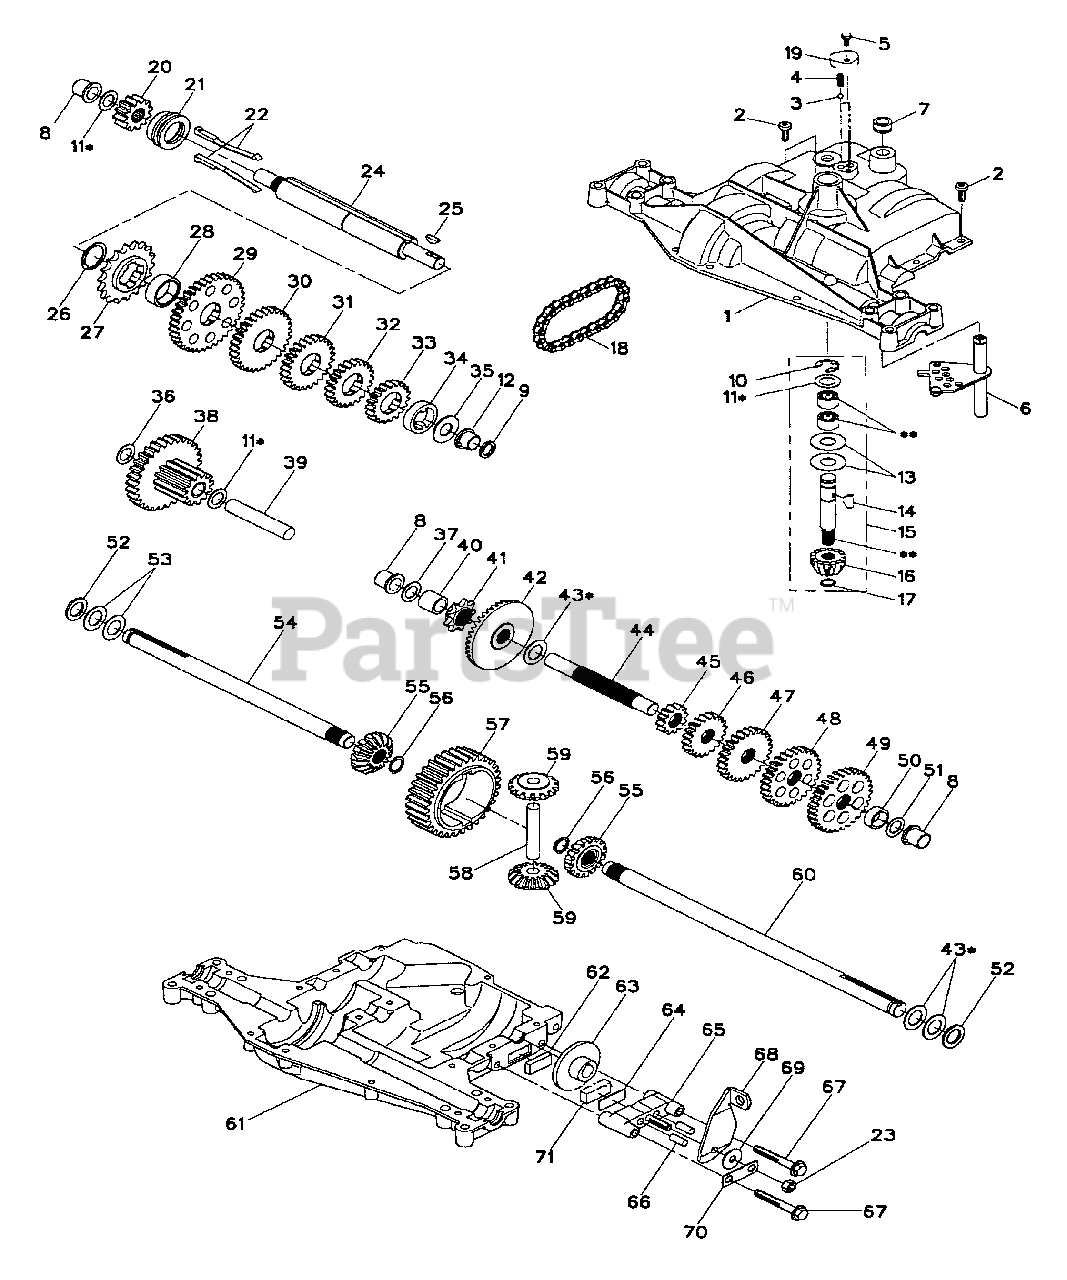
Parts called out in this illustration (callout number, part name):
1	Housing, Upper
2	Screw, Tapping, 1/4-20 X .734
3	Ball, Detent
4	Spring, Detent
5	Screw, Tapping, No.10-24 X .482
6	Assy, Shifter
7	V-Ring
8	Bearing, Flange
9	Seal, Oil
10	Ring, Retaining
11	Assy, Kit, Shim, .625 Shaft
12	Bearing, Flange
13	Washer, Plain, .632 X 1.38 X .046
14	Key, Woodruff, No. 9
15	Assy, Kit, Input Shaft
16	Pinion, Bevel, 12T
17	Ring, Retaining
18	Chain, 24 Pitches
19	Cover, Detent
20	Gear, Spur, 12T
21	Collar, Clutch
22	Assy, Kit, Clutch Keys
23	Nut, Lock, 5/16-24
24	Shaft, Intermediate
25	Key, Woodruff, No. 61
26	Ring, Retaining
27	Sprocket, 18T
28	Spacer, 1.131 X 1.45 X .494
29	Gear, Spur, 37T
30	Gear, Spur, 30T
31	Gear, Spur, 25T
32	Gear, Spur, 22T
33	Gear, Spur, 19T
34	Spacer, 1.133 X 1.50 X .375
35	Washer, Plain, .640 X 1.37 X .061
36	Washer, Plain, .632 X 1.00 X .046
37	Washer, Plain, .632 X 1.00 X .031
38	Assy, Gear, Comb., 12T & 30T
39	Shaft, Idler
40	Spacer, .633 X .87 X .755
41	Sprocket, 9T
42	Gear, Bevel, 36T
43	Assy, Kit, Shim, .750 Shaft
44	Shaft, Drive
45	Gear, Spur, 12T
46	Gear, Spur, 20T
47	Gear, Spur, 25T
48	Gear, Spur, 28T
49	Gear, Spur, 31T
50	Spacer, .781 x 1.00 x .375
51	Washer, Plain, .632 X 1.00 X .060
52	Washer, Neoprene
53	Washer, Plain, .758X 1.25X .031
54	Axle, LH
55	Gear, Miter, 12T
56	Ring, Retaining
57	Gear, Spur, 32T
58	Shaft, Cross
59	Gear, Miter, 12T
60	Axle, RH
61	Housing, Lower
62	Puck, Friction
63	Disc, Brake
64	Spacer, Brake Puck
65	Jaw, Brake
66	Pin, Dowel
67	Screw, Tapping, 5/16-18 X 2.35
68	Lever, Actuating
69	Washer, Plain, .321 X 1.00 X .055
70	Bracket, Anti-Rotation
71	Puck, Friction
